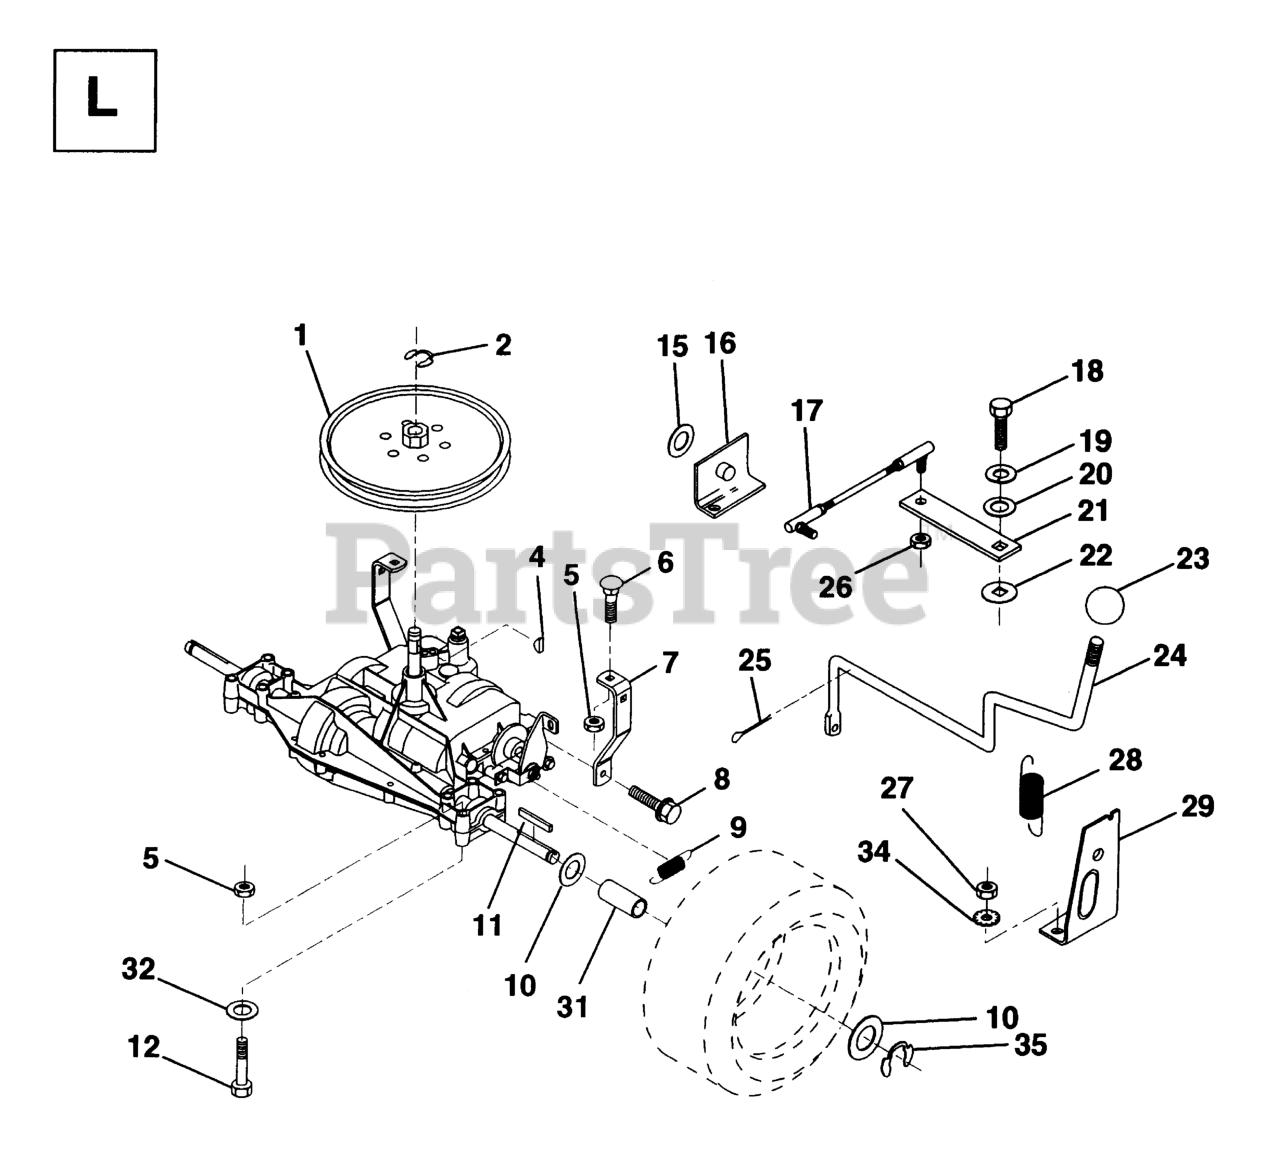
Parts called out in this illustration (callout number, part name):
2	RETAINING RING LT
4	KEY STD (1373) DANA
5	LOCKNUT
6	RP BOLT 5/16-18 X3/4 ZN/YEL GR
7	STRAP,TORQUE
8	SCREW.THDROL.5/16-18X3/4.TTY
9	SPRING T
11	SQUARE KEY
12	Bolt, Hex, Fin. 5/16 x 18 UNC x 2-1/2
15	WASHER
16	SUPT, HDLE SHT LH
19	LOCKWASHER
22	WASH-SHFT PLT LT
23	KNOB.DUCKHEAD.1/2
23	KNOB T (1/2-HOLE)
24	ROD, SHIFT
25	PIN COTTER
26	LOCKNUT
27	NUT
28	SPRING.EXTENSION
29	SUPPORT HANDLE SHAFT RH
31	SPACER AXLE
32	WASHER
34	WASHER EXT TOOTH LOCK 5/16
